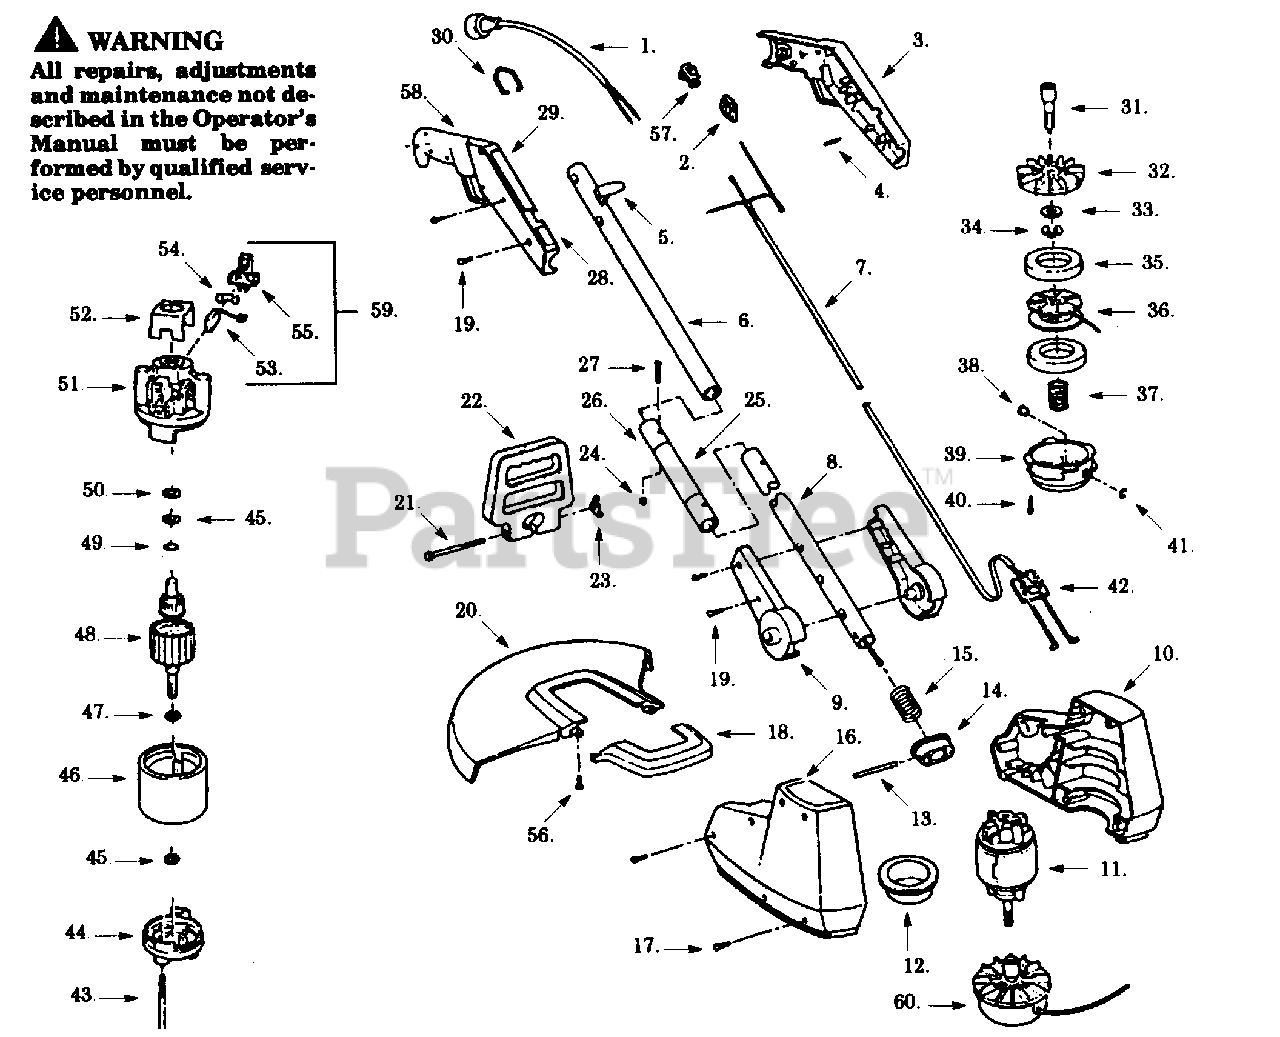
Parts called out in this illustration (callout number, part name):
1	Power Cord
2	Trigger Switch
3	R.H./L.H. Handle
4	Hinge Pin
5	Cable & Lever Ass'y.
6	Upper Tube
8	Lower Tube
9	R.H./L.H. Pivot
10	R.H./L.H. Housing
12	Air Baffle
13	Sleeve Pin
15	Sleeve Spring
16	Hsg. Top Label
18	Front Guard
20	Guard & Blade Ass'y.
22	Assist Handle
23	Wing Nut
24	Stop Nut
25	Warning Label (Not a serviceable part)
26	Outer Tube
28	Inch Cut Label (Not a serviceable part)
29	Handle Label (Not a serviceable part)
31	Drive Adapter
32	Rear Plate
34	Retaining Ring
35	Foam Pad
36	Spool & Line
39	Hub Ass'y.
40	Cotter pin
41	Wire Ring
42	P.C. Bridge
44	Endbell Ass'y. (Drive)
46	Field Ass'y.
47	Retaining Ring
48	Armature Ass'y.
49	Retaining Ring
51	Endbell Ass'y. (Brush)
52	Insulator
54	Brush Spring
55	Brush Holder
57	Power Switch
58	Torque Booster Label (Not a serviceable part)
59	Brush Kit (Incl. 53,54,55)
60	Cutting Head Ass'y.
